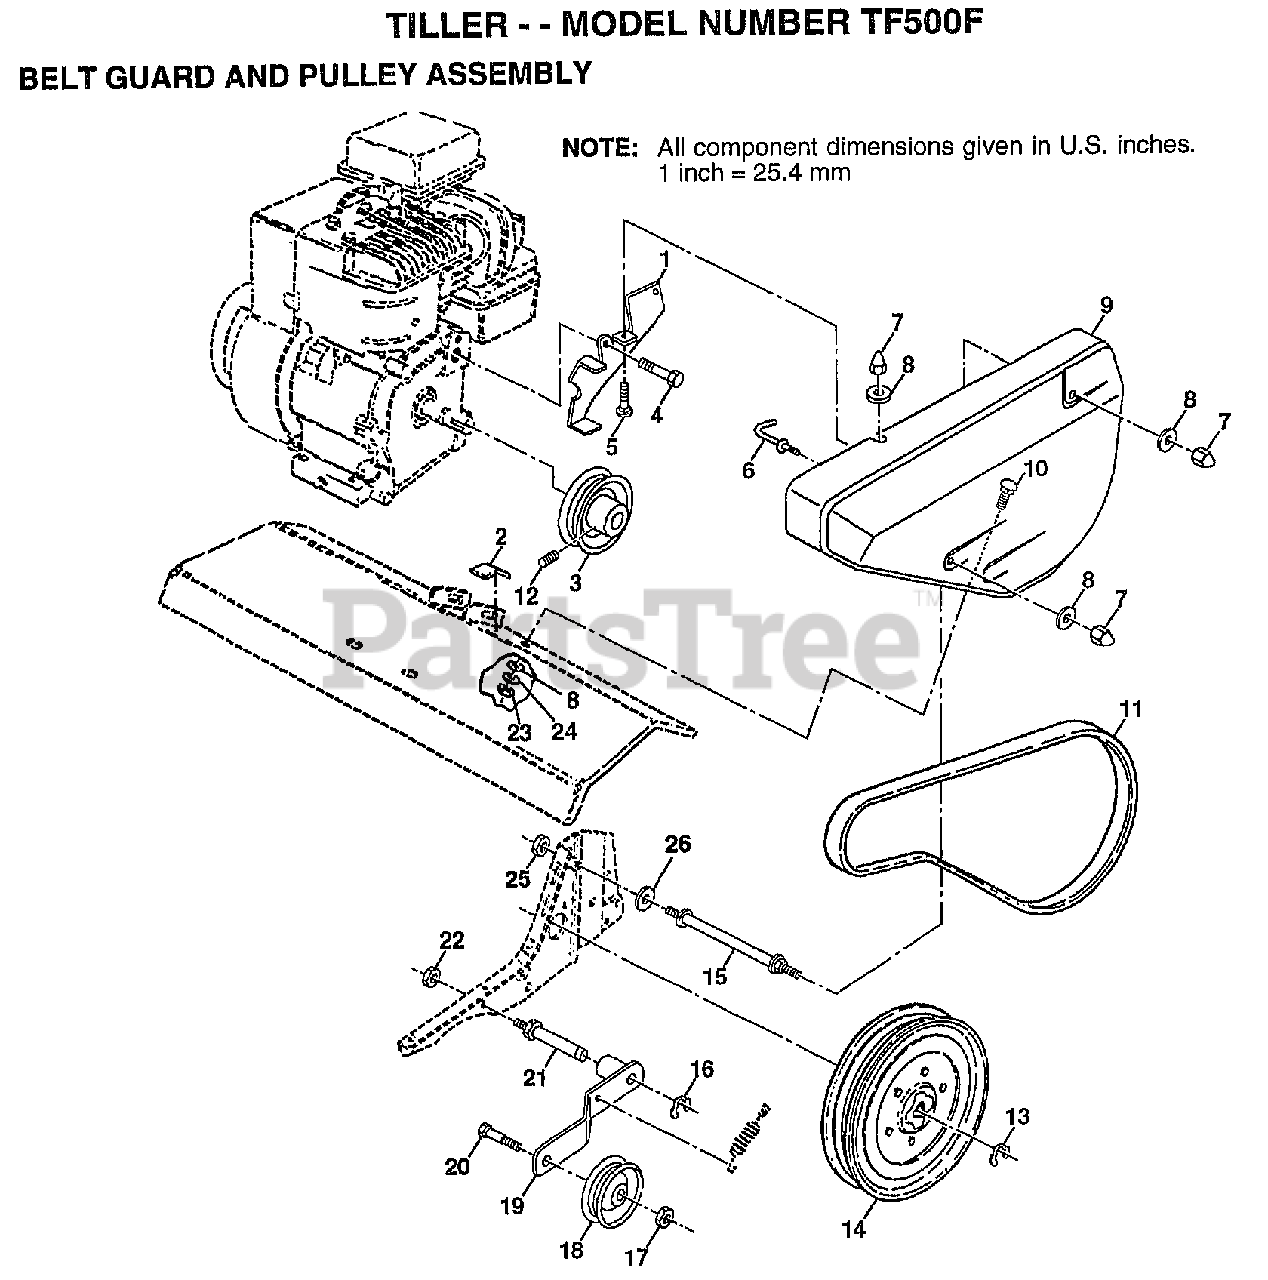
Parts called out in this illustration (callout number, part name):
1	BRKT GUARD BELT
2	PAD IDLER TI
3	ENGINE PULLEY
4	BOLT.HEX.HEAD
5	BOLT
7	NUT-CAP TI
8	WASHER
9	GUARD.PNT.BELT
10	BOLT T
11	V BELT STD
12	SET SCREW
14	SHEAVE.TRANS
15	BOLT TI
16	KLIP RING TI
17	NUT
18	"PULLEY,IDLER"
19	"ARM, IDLER"
21	SHAFT IDLER TI
22	JAM NUT TI
24	LOCKWASHER
25	NUT
26	WASHER
